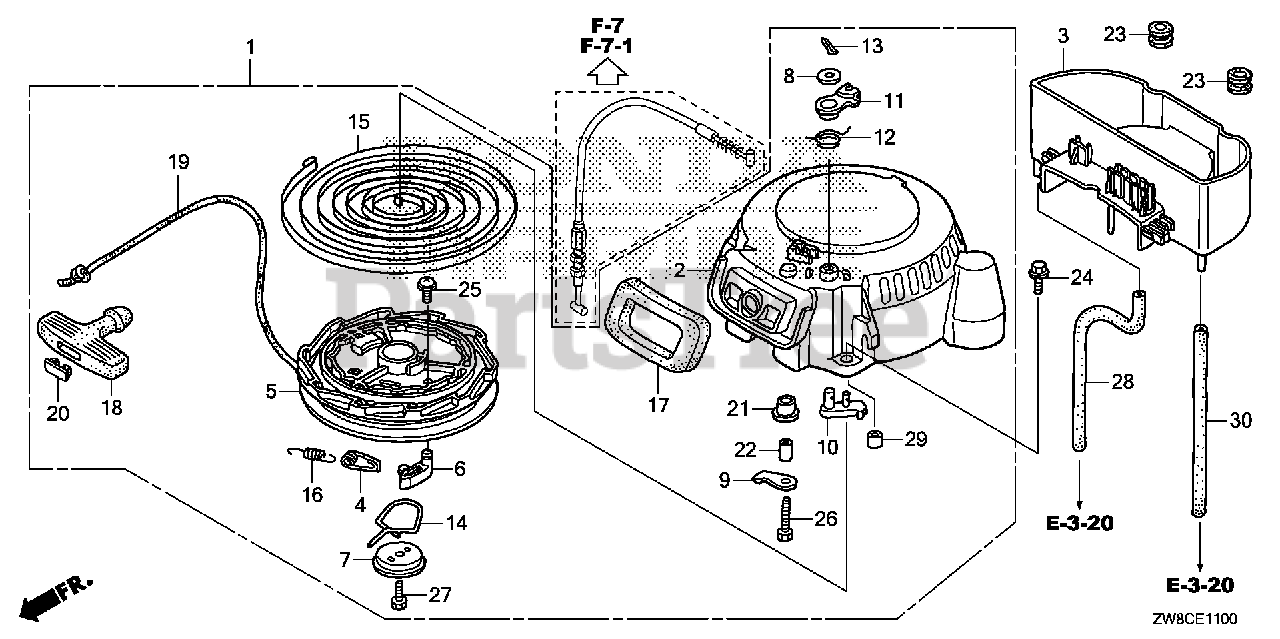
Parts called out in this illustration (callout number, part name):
1	STARTER ASSY., RECOIL
2	CASE, RECOIL STARTER
3	CASE B, STARTER
4	GUIDE, RECOIL STARTER
5	REEL, RECOIL STARTER
6	RATCHET, STARTER
7	PLATE, FRICTION
9	WASHER, THRUST
10	STOPPER, REEL
11	ARM, STOPPER
12	SPRING, STOPPER
13	PIN, SPLIT
14	SPRING, FRICTION
15	SPRING, RECOIL STARTER
16	SPRING, RETURN
17	SEAL, RECOIL
18	GRIP, STARTER
19	ROPE, RECOIL STARTER (N/A: USE P/N 08550-ZG921-11)
20	CAP, STARTER KNOB
21	ROLLER, STARTER
22	GUIDE, ROLLER
23	GROMMET, ENGINE COVER
24	BOLT, FLANGE (6X22)
26	BOLT, HEX. (6X25)
27	BOLT, HEX. (6X14)
28	TUBE, WATER DRAIN
29	COLLAR (6.5X11X10)
30	BULK HOSE, VACUUM (8X1000) (8X240)
